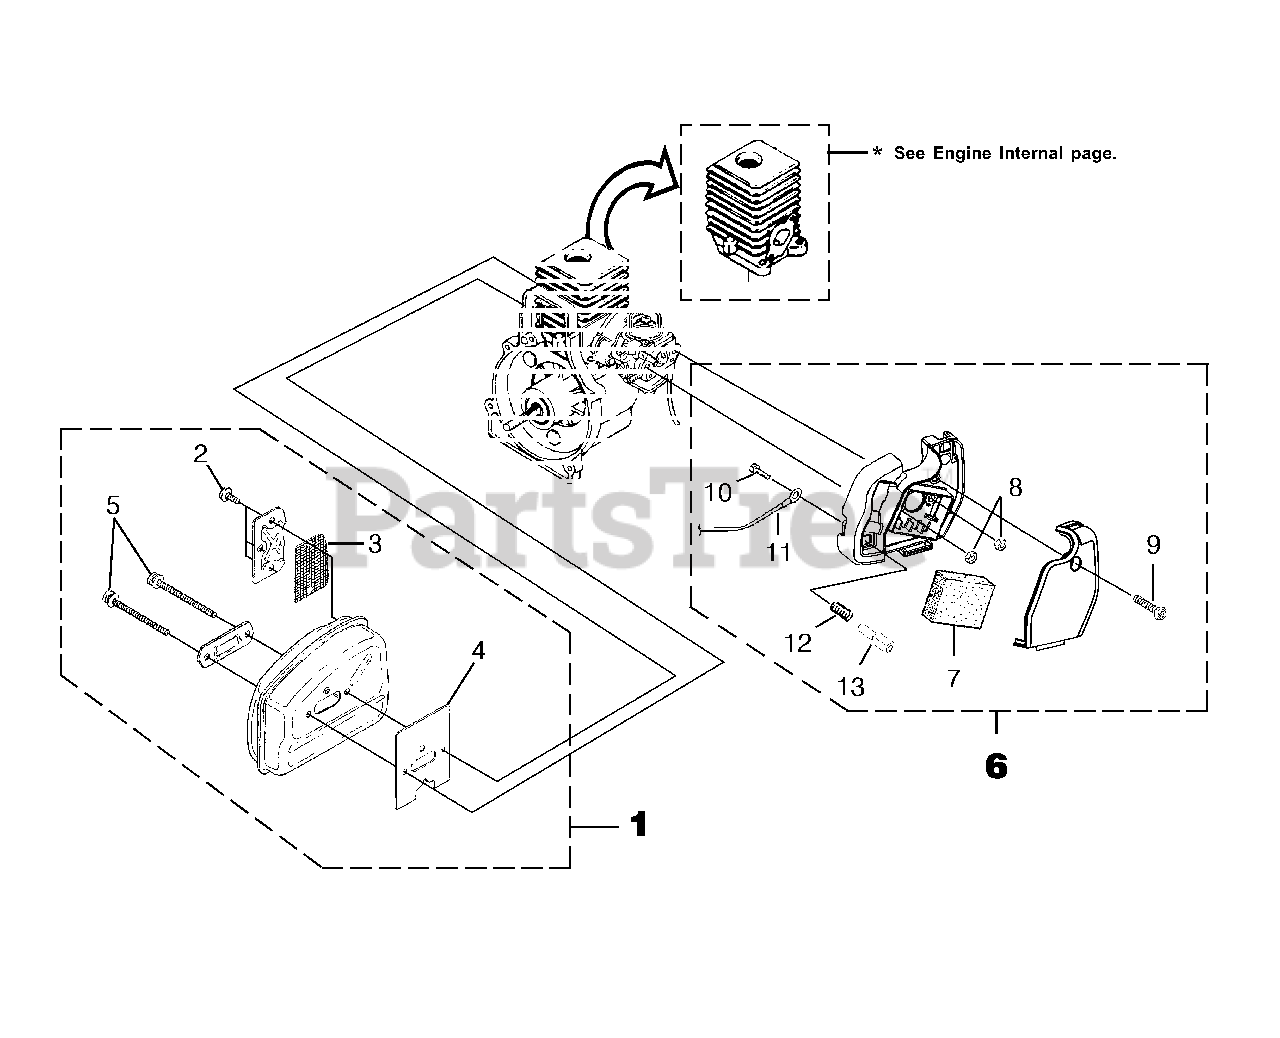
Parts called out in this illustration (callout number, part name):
1	MUFFLER ASSY.
2	SCREW, Taptite- (8-32 X 3/8")
3	SCREEN-Spark
4	GASKET-Muffler
5	SCREW, Truss Hd. - (10-24 X 2.188)
6	AIR FILTER KIT
7	FILTER-AIR
8	NUT-Hex (10-24)
9	SCREW-Slotted Tr. Hd (8-16 x
10	SCREW-Thread Form (6-19 x 1/2")
11	LEAD-Electrical
12	SPRING-Compression
13	BUTTON-Switch
